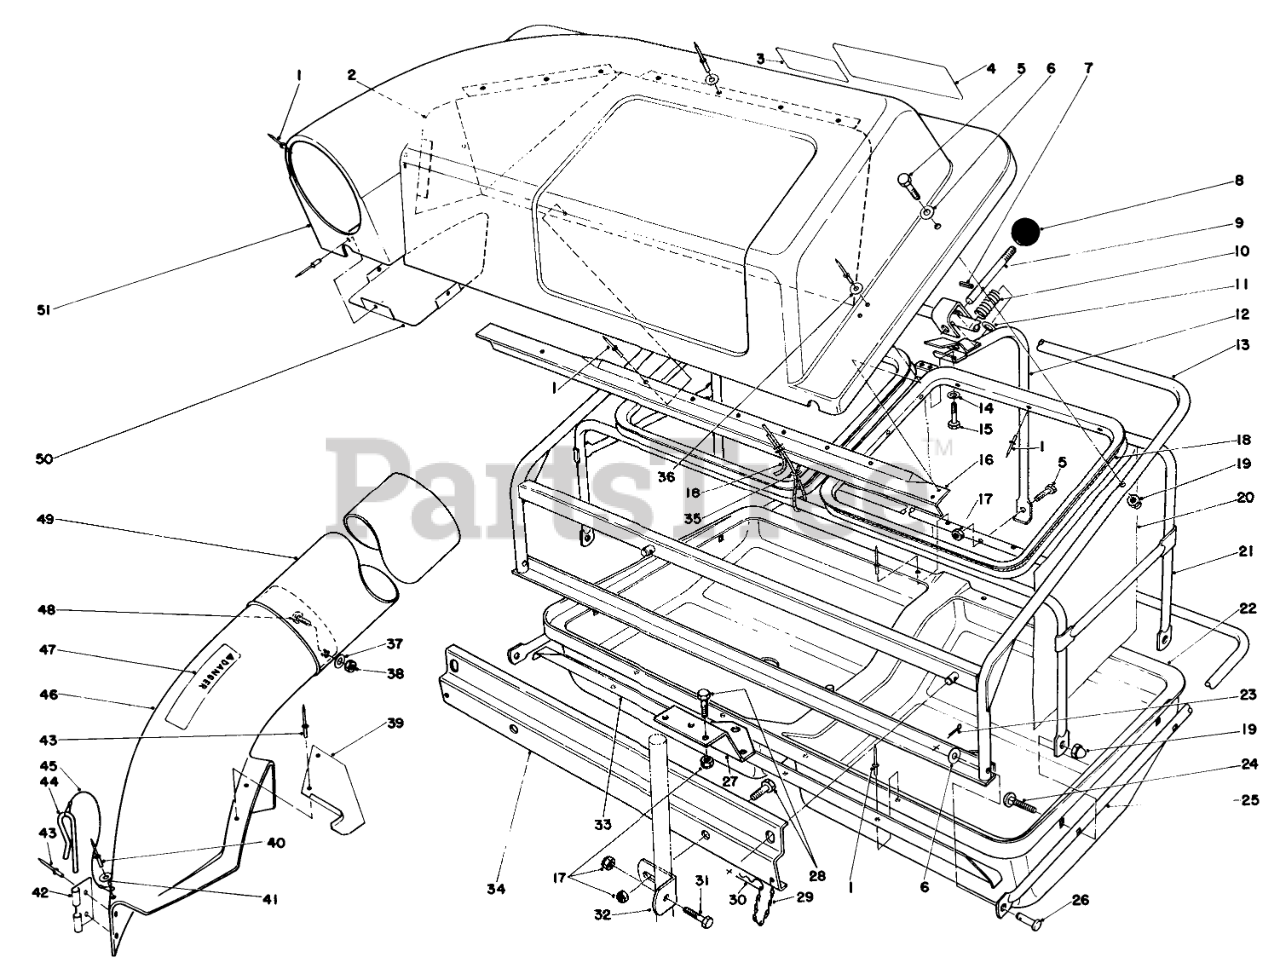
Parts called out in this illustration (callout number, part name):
2	Screen Cover
3	LATCH DECAL
4	EASY FILL DECAL
5	SCREW-HH
6	WASHER-PLAIN
7	PIN-ROLL, SLOT
9	Lever-Latch
10	Compression Spring
11	WASHER-FLAT
12	Handle Assembly
13	Frame Assembly
14	WASHER-LOCK
15	SCREW-HH
16	Bracket Screen Support
17	NUT-LOCK, CONE
18	RETAINER CORD
19	NUT-LOCK, CAP
20	Curtain
21	Bag Support Assembly
22	Hopper
23	PIN-COTTER
24	SCREW-CARR
25	HOPPER SUPT TUBE B
26	CLEVIS
27	Plate-Mtg. Grass Catcher
28	SCREW-HH
29	6-LINK CHAIN W/HOOK
30	PIN-HAIR
31	SCREW-HH
32	Bracket Mtg. Grass Catcher
33	HOPPER SUPT STRAPB
34	Bracket Frame Support
35	COUPLER
36	WASHER-FLAT
37	WASHER-FLAT
38	NUT-KEPS
39	CHUTE SUPT BRKT
40	RIVET-BLIND
41	WASHER-PLAIN
42	BRACKET-MOUNTING, CHUTE
43	RIVET-BLIND
44	PIN-LOCKING, CHUTE
45	LANYARD
46	Chute Assembly (Incl. Ref. #39-45 & 47)
47	Decal-Chute
48	BOLT-CARR
49	Duct
50	Shield Cover
51	Cover
